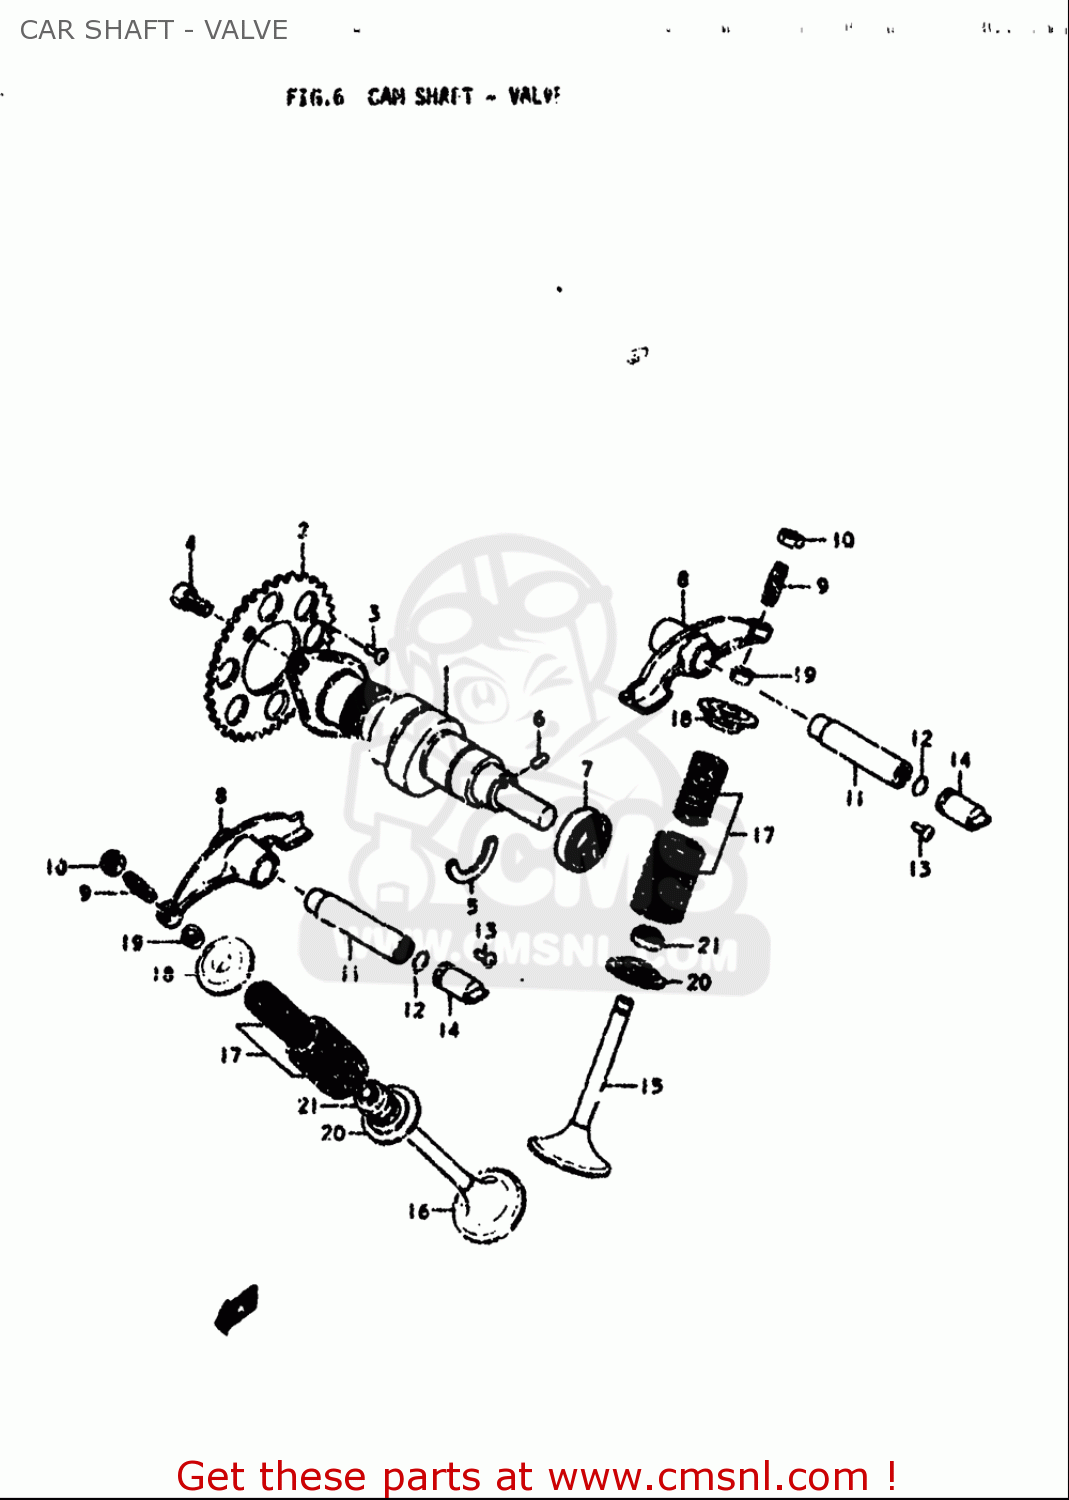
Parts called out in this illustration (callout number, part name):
1	CAMSHAFT
2	SPROCKET,CAMSHAFT
3	SCREW(5X6)
4	BOLT,VAC.PIPE
5	C RING
6	PIN
7	OIL SEAL (18X30X7)
8	ARM,VALVE ROCKER
9	SCREW,TAPPET ADJUSTING
10	NUT,ADJUSTING SCREW
12	O RING(D:1.9,ID:8.6)
13	SCREW
15	VALVE,INTAKE
16	VALVE,EXHAUST
17	SPRING SET,VALVE
18	RETAINER,VALVE SPRING
19	COTTER VALVE
20	SEAT,VALVE SPRING
21	SEAL,OIL(7X14.4X9)
